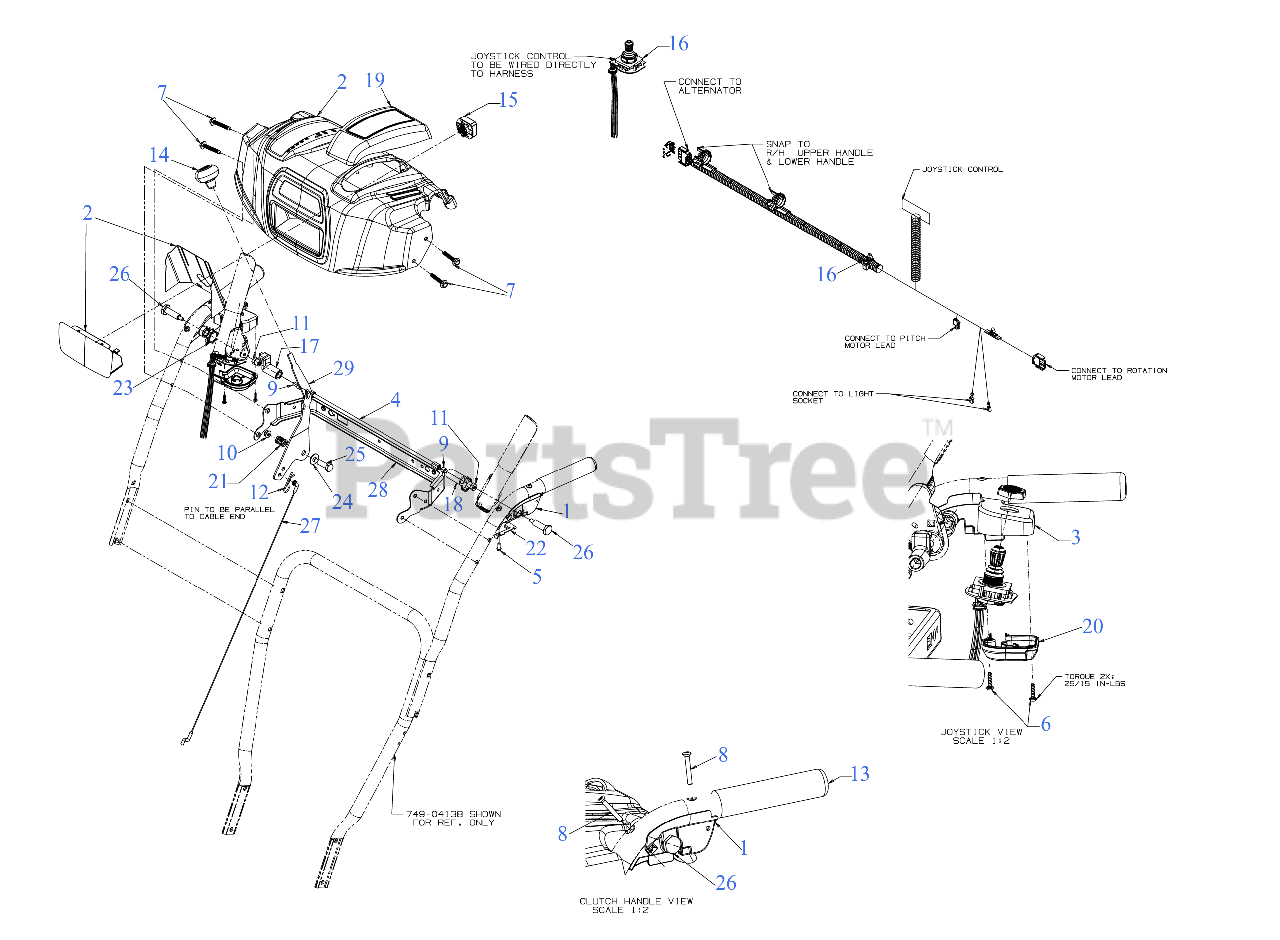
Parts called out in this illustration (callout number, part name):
1	CLUTCH LOCK HANDLE ASSEMBLY (LH)
2	HANDLE PANEL ASSEMBLY
3	CLUTCH HANDLE ASSEMBLY (RH)
4	PIVOT ROD
5	SCREW #8-16 x .50
6	SCREW .159 x .610
7	SCREW 1/4-20 x 1.625
8	SCREW #10-24 x 1.375
9	SCREW 1/4-20 x .50
10	FLANGE LOCK NUT
11	HEX NUT W/PATCH
12	INTERNAL COTTER PIN
14	SHIFT KNOB
15	LED HEADLIGHT SOCKET (150 LUMNES)
16	4-WAY ELEC CHUTE HARNESS
17	LOCK PLATE
18	CLUTCH LOCK CAM
19	HANDLE COVER PANEL
20	JOYSTICK HOUSING COVER
21	COMPRESSION SPRING
22	CLUTCH SPRING
23	TORSION SPRING
24	FLAT WASHER .40X.88X.060
25	SHOULDER SCREW
26	SHOULDER SCREW .437 x 1.345 1/4-20
27	SPEED SELECTOR CABLE (PLASTIC)
28	HANDLE SUPPORT BRACKET (POWDER BLACK)
